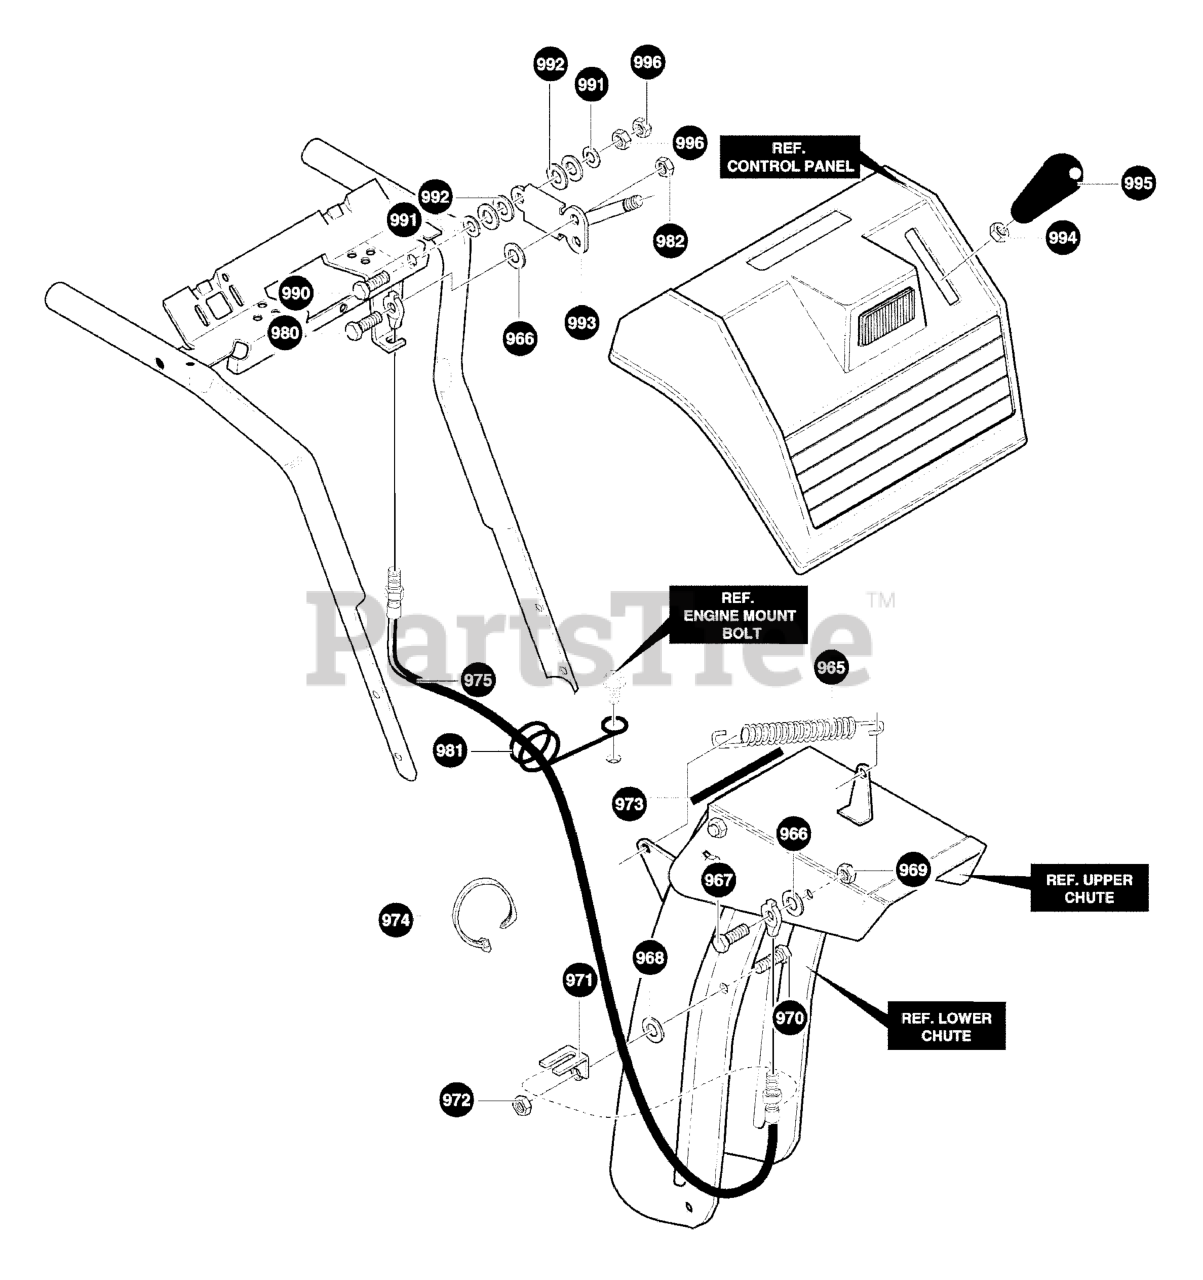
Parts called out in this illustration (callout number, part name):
965	SPRING, TENSION RETURN
966	WASHER, FLAT
967	BOLT, 5/16-18
968	WASHER, FLAT
969	NUT, 1/4-20
970	SCREW, 5/16-18 x 0.75
971	BRACKET, CABLE CHUTE
972	NUT, 5/16-18
973	TRIM,STRIP, BLACK
974	TIE, CABLE
975	CABLE, CHUTE CONTROL
980	BOLT, 5/16-18
981	WIRE FORM
982	NUT, 1/4-10
990	SCREW, 3/8-16 x 1.75
991	WASHER, FLAT
992	WASHER, SPRING
993	HANDLE ASSY, SPEED CTRL
994	NUT, 3/8-16 REGHEX
995	HANDLE, 3/8-16 MOLDED TALL
996	NUT, 3/8-16 HEXNYL
